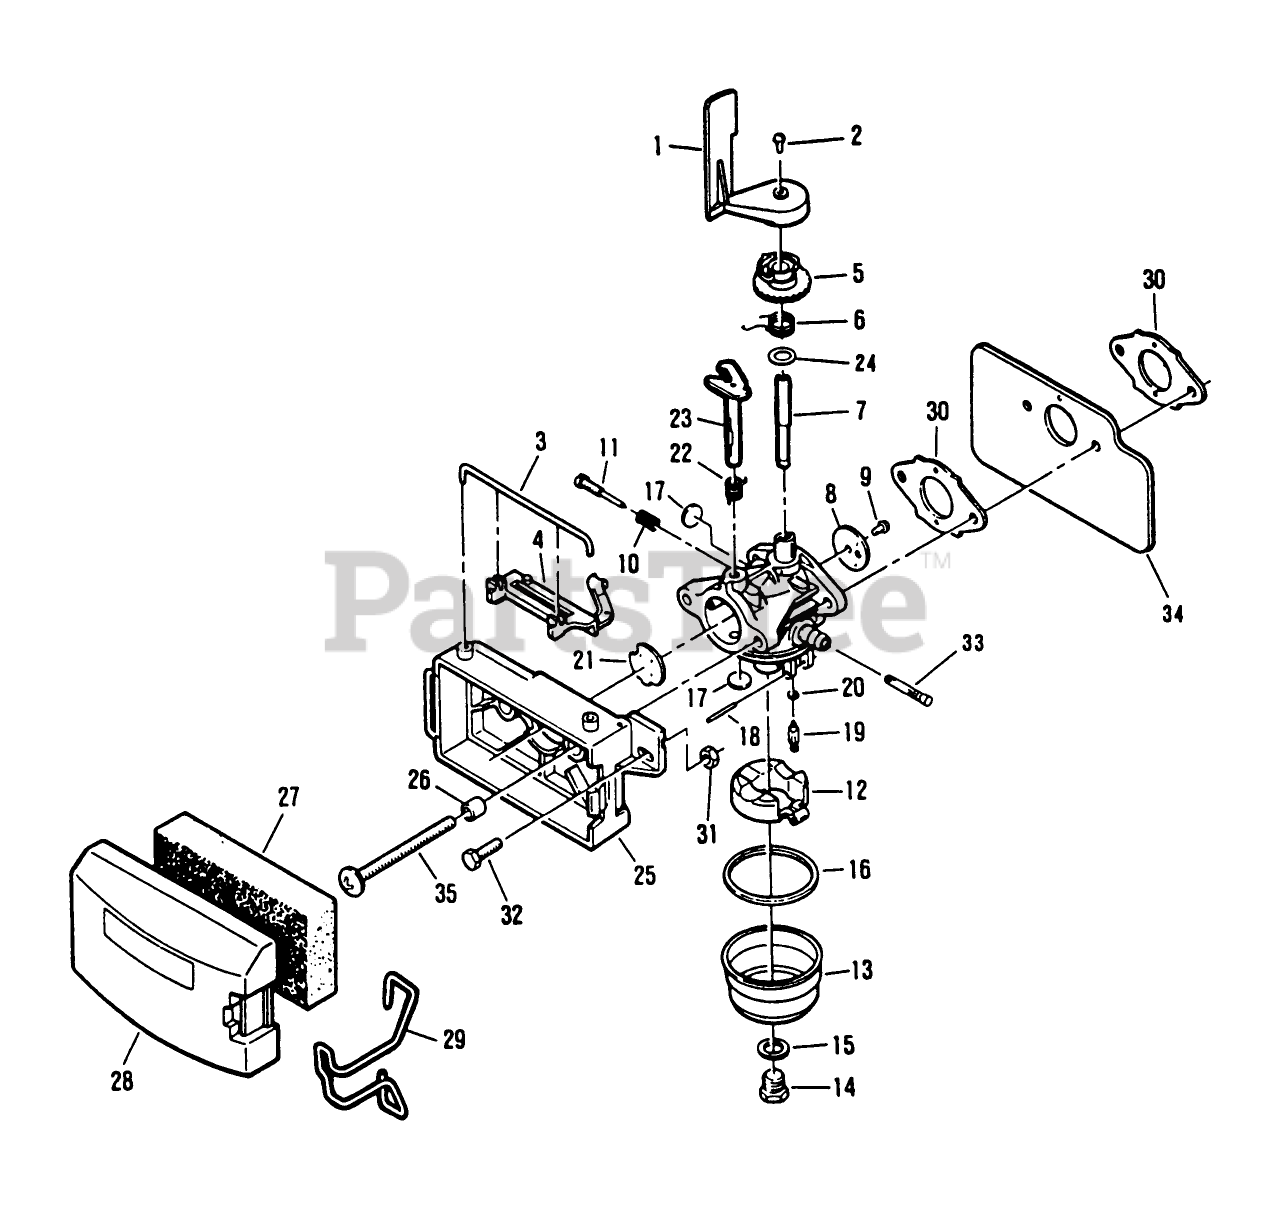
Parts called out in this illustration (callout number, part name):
1	AIR VANE F
2	SCREW F
3	RETAINER
5	COLLAR A/VAVE F
6	THROTTLE SPR E
7	Shaft-Throttle
8	Valve-Throttle
9	Screw-Throttle Valve
10	Spring-Idle Needle
11	Needle-Idle
13	Bowl-Fuel
14	Screw-Bowl Retainer
15	Gasket-Bowl Retainer
16	Gasket-Fuel Bowl
17	Plug-Welch
18	Shaft-Float
19	Valve-Inlet Needle
20	Seat-Valve
21	Valve-Choke
22	Spring-Choke Return
23	Shaft-Choke
24	WASHER VF
26	SPACER
29	RETAINER-COVER, FILTER
30	GASKET CARB S
32	SCREW
33	SCREEN FUEL PITTS
34	SHIELD, CARB F
35	SCREW
